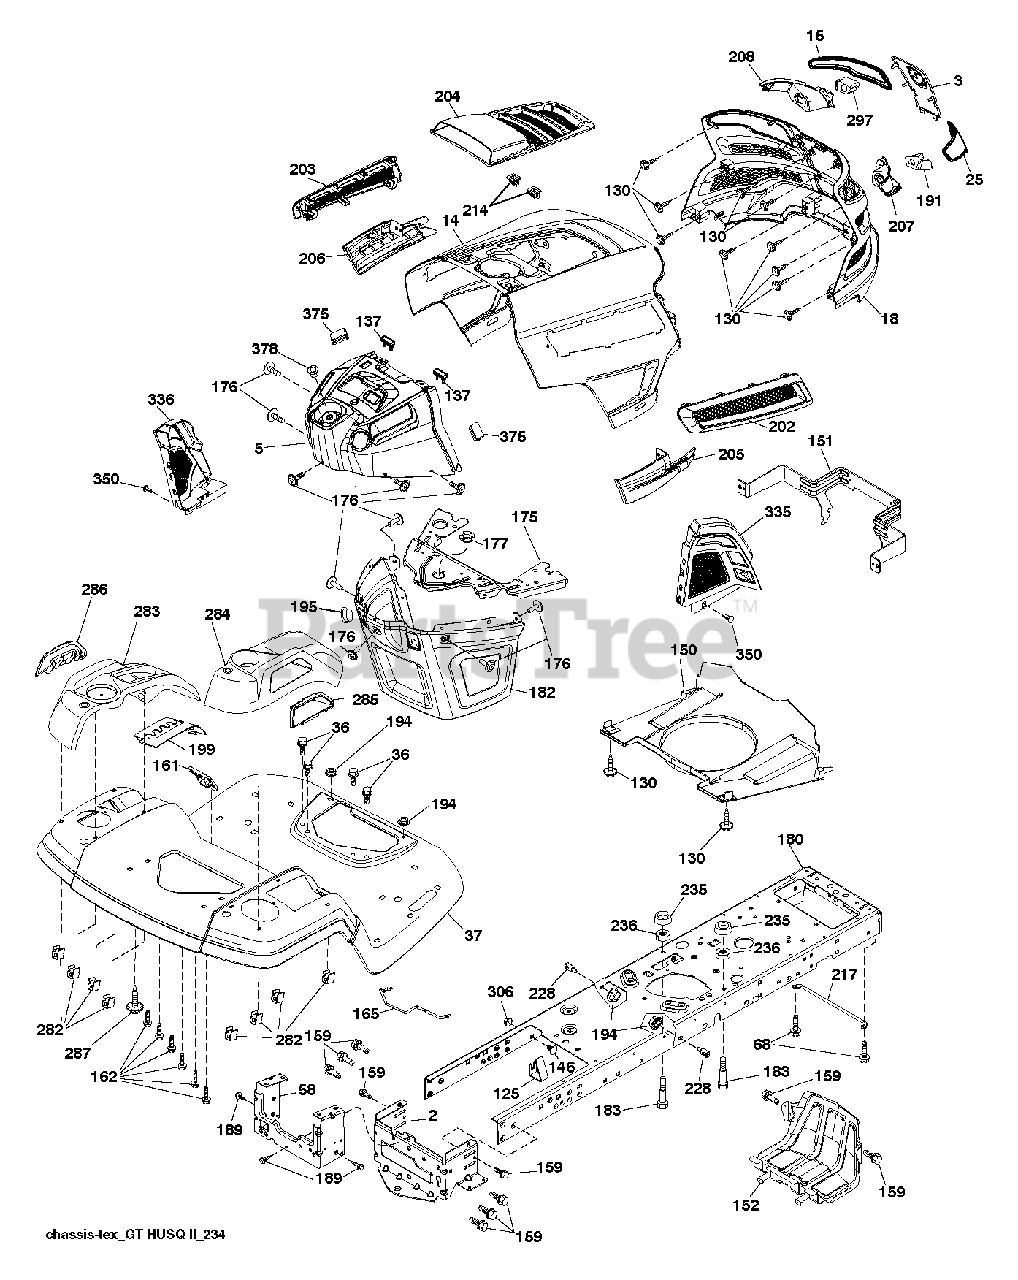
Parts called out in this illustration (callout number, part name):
2	DRAWBAR.LOWER.2PC.18/22
3	APPLIQUE.SUBASM.GT.HUSQ.II
5	DASHBOARD.TEX.GT2.UPPER.S.PTO
14	HOOD.ASM.HUSQVARNA.GT.TEX.ORAN
15	LENS.HEADLIGHT.LH.GTII.2011
18	GRILLE SUBASM.GT.II.LOW.HDLGHT
25	LENS.HEADLIGHT.RH.GTII.2011
36	SCREW 5/16"
37	FENDER.TLT.FS.W/CPH/FW/RSF.668
58	DRAWBAR UPPER 2PC SMALL FENDER
68	SCR 5/16-18 X 1/2 SELFTAP ZN
125	CLIP.FUEL.LINE
130	SCREW.#10 X 0.750.BOS
137	BUMPER DASH
146	BOLT.RDHD.SHT.SQNK.3/8-16X5/8
150	AIR.DUCT.GTV.BLACK
151	BRACKET.PIVOT.HOOD.GT.HUSQ.II
152	SHIELD.BROWNING.PNT.GT.V2
159	SCREW, 3/8-16X3/4
161	WINDOW.FUEL.LT.HUSQ.TEX.498
162	SCREW.HI-LO.CONSOLE
165	SUPPORT.TANK.REAR.B/TE
175	Crossmember Plate
176	SCREW.#10-24X5/8.RN.QU
177	BUSHING STEERING
180	CHASSIS.LT/GT.BOLTED
182	DASH.LOWER.COMMON.12V.ADAPTOR
183	BOLT.5/16-18X1-1/4 FULL THD
189	SCREW
191	INSERT.REFLECTIVE.RH.HUSQ.GTII
194	NUT LOCK HEX FLANGE 5/16-18
195	PLUG.HOLE.DASH.LOWER.12V.BLK
199	PLATE.DECK.LIFT.HUSQ.LT
202	VENT.SIDE.RH.GT.HUSQ.II.
203	VENT.SIDE.LH.GT.HUSQ.II.498
204	VENT.TOP.HUSQ.GT2
205	SIDE.TRIM.RH.GT.HUSQ.II
206	SIDE.TRIM.LH.GT.HUSQ.II.GRAY
207	HEADLIGHT.CUP.BEZEL.HUS.GT2.RH
208	HEADLIGHT.CUP.BEZEL.HUS.GT2.LH
214	CLIP.RETAINER.TINNER.
217	ROD.PIVOT.HOOD
228	STUD.FASTNER.W/ANTI-ROTATE
235	SPACER FENDER
236	NUT.CENTERLOCK.5/16-
282	CLIP.RETAINER.CONSOLE.LT.HUSQ
283	CONSOLE.DECK.LIFT.R.SDFL.HUSQ
284	CONCOLE.CNTRL.PDL.HUSQ.LT.498
285	CONSOLE INSERT RH
286	CONSOLE.INSRT.LH.HUSQ.LT.BLACK
287	SCREW 1/4X20
297	INSERT.REFLECTIVE.LH.HUSQ.GTII
306	NUT LOCK FLG 3/8-16 UNC
335	COVER.LOWER.DASH.RH.BLACK
336	COVER-LH.LOWER.DASH.GT2.BLACK
350	CLIP.X-MAS.TREE
375	BUMPER CLIP-ON. DASH 1"
378	BUSHING FLANGE; PLASTIC
